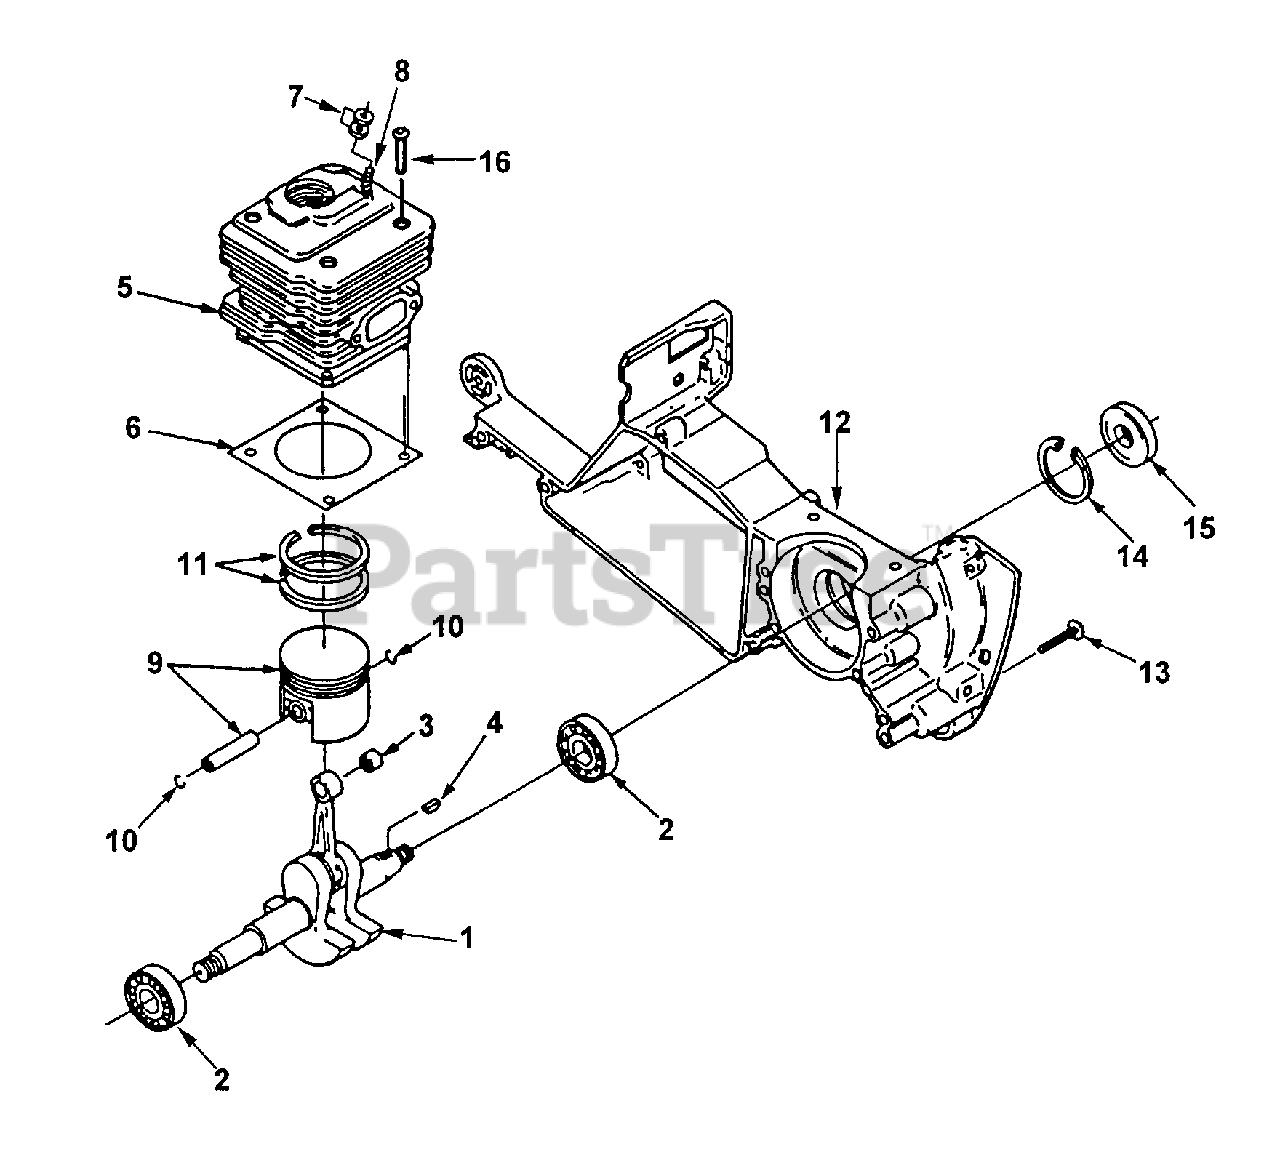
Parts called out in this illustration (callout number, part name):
1	CRANKSHAFT
2	BEARING-Ball
3	BEARING-Piston Pin
4	KEY-Woodruff
5	CYLINDER & PISTON ASSEMBLY
6	GASKET-Cylinder
8	STUD-(10-24 X 1 1/4")
9	PISTON (1.890 Dia.)
10	RING-Retaining
11	RING-Piston
12	CRANKCASE
13	SCREW-Truss Hd. (10-24 X 1 1/4")
14	RETAINER-Bearing
15	SEAL-Main
16	SCREW-Pan Hd (12-24 x 3/4")
